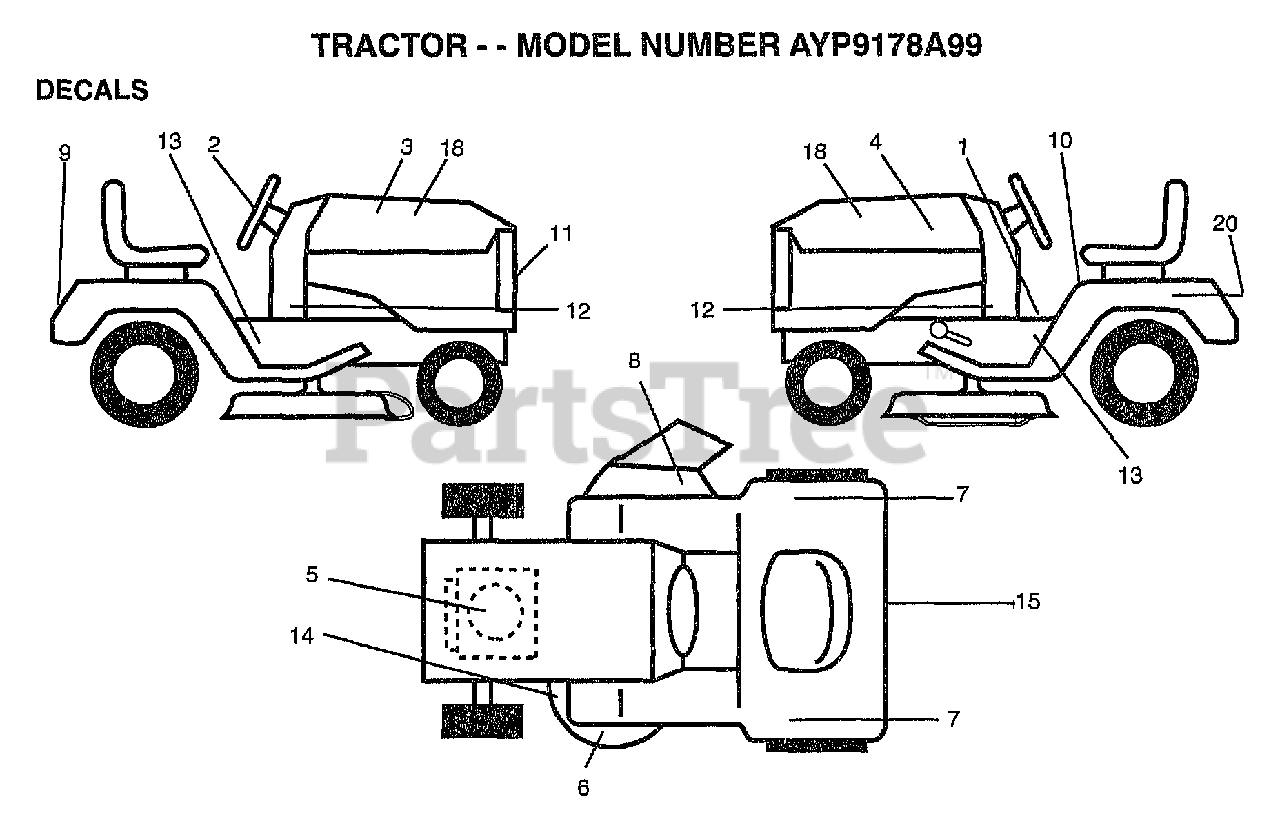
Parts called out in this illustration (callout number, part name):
1	"DEAL-OPER,INST."
2	DECAL STEER WHL
3	DECAL HOOD RH
4	DECAL HOOD LH
5	DECAL, HP ENGINE
6	DECAL DECK MULCH
7	DECAL.FENDER.AUTO
8	DECAL DECK WIZ +
10	"DECAL DANGER,FEND"
11	DECAL.LENS.WIZARD
12	DECAL.SIDE PANEL
13	"DECAL.CHASSIS.42"""
14	"DECAL-SCHEM,BELT"
15	DECAL DRAWBAR LH
18	NAMEPLATE.HD.WIZA
20	DECAL.BATRY.3-3908
